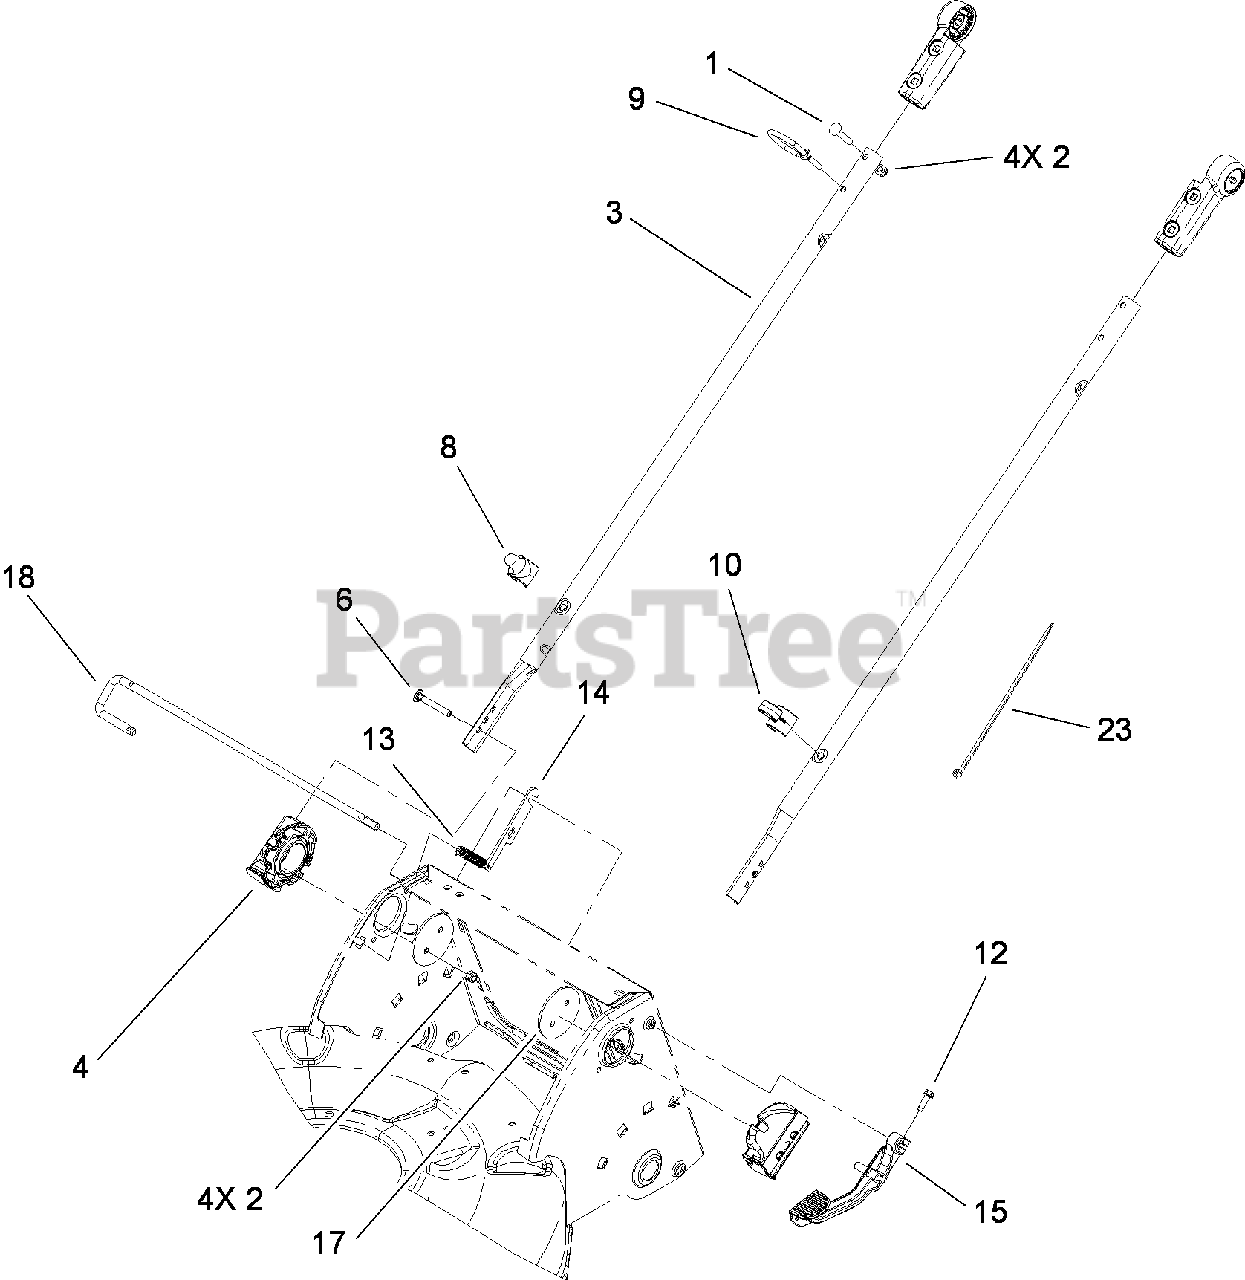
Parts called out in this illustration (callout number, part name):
1	SCREW-CARR
2	NUT-LOCK, NI
4	HANDLE-MOUNT, LOWER
8	GUIDE-ROPE, LOWER
9	GUIDE-ROPE, UPPER
10	Guide-Cable
12	SCREW-HWHTF
13	SPRING-EXTENSION
14	PLATE-RELEASE ROD
15	LEVER-RELEASE
18	ROD-HANDLE RELEASE
23	STRAP-TIE
